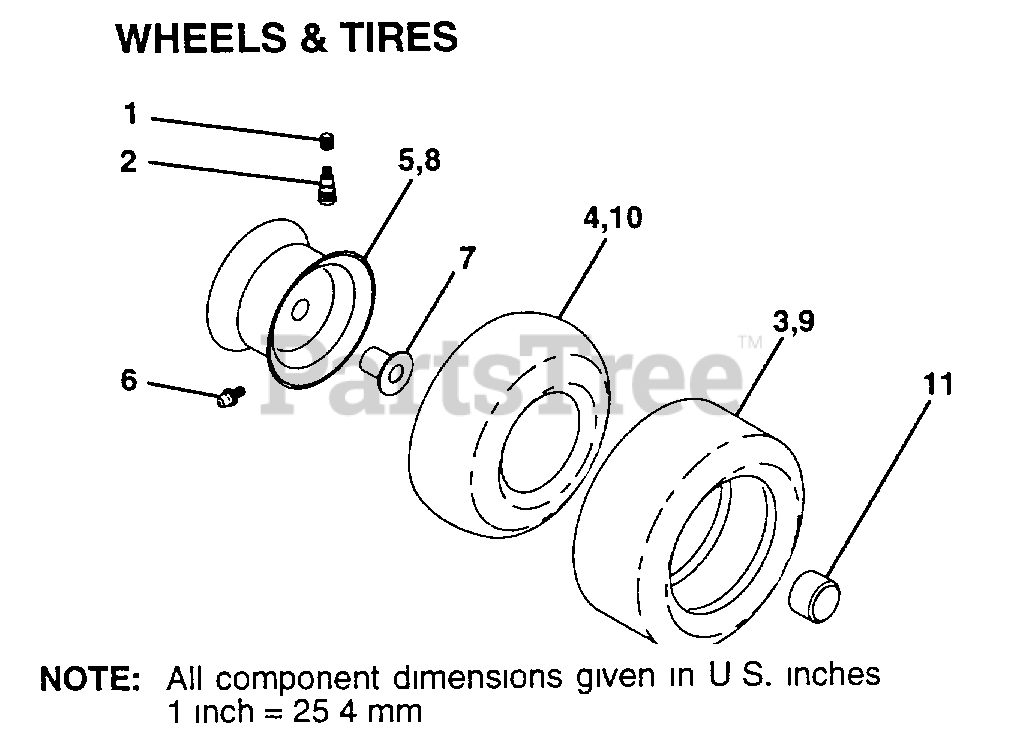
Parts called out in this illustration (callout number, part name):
1	VALVE CAP
2	VALVE STEM LT
4	TUBE.5.3/4.5/6
5	RIM.FRONT.6.YELLO
6	FITTING LT
7	"FLANGE, BEARING"
10	TUBE.18X9.5-8
11	HUB CAP
